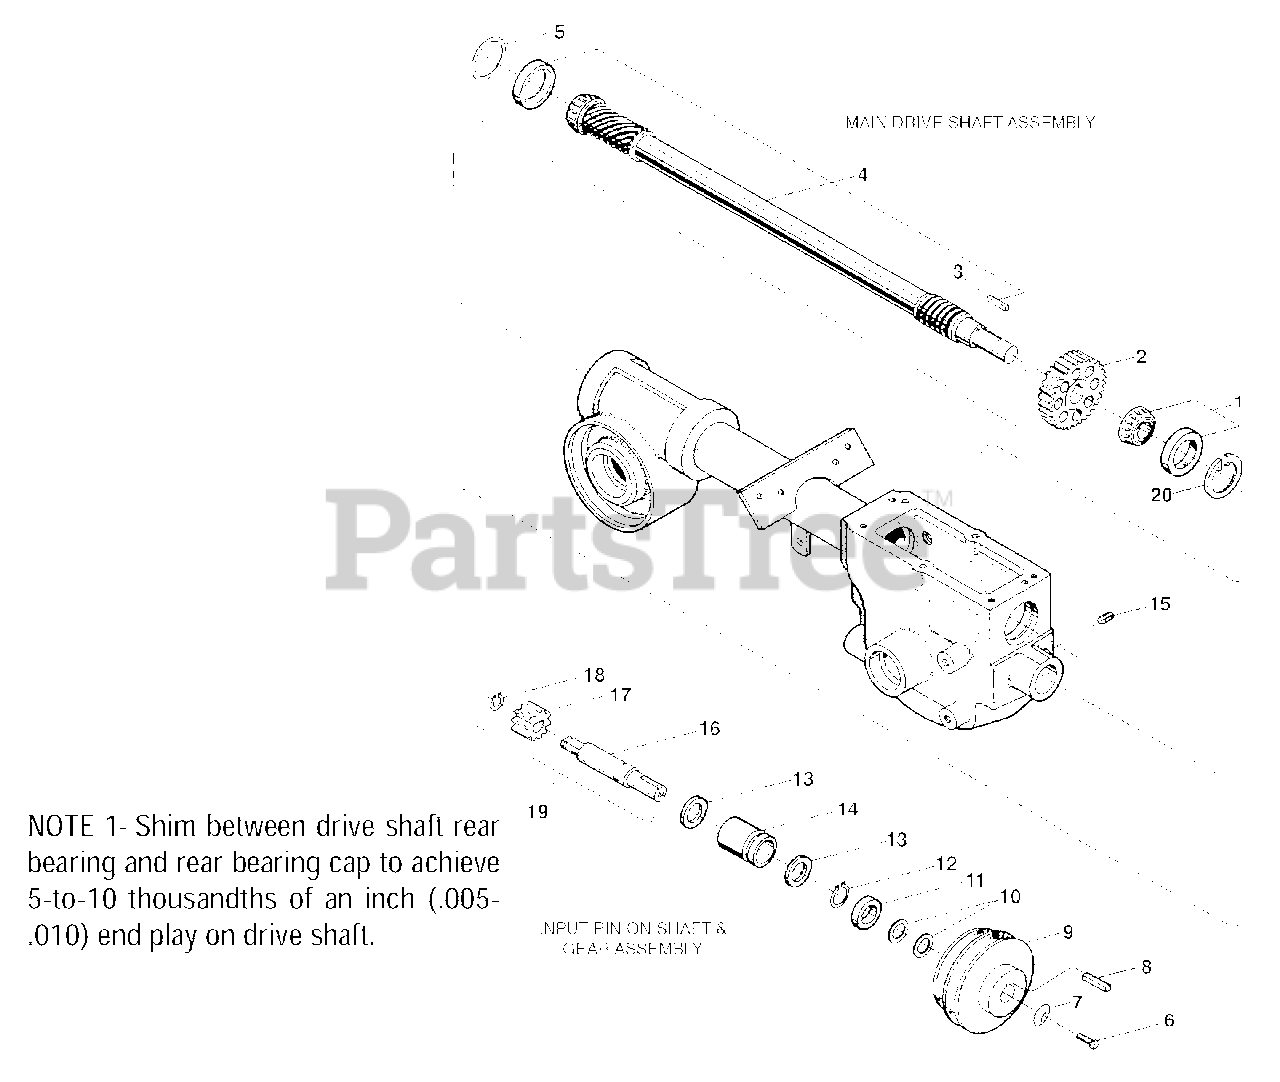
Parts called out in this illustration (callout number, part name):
1	Bearing-Tapered roller with race
2	Gear-Spur, main drive shaft
3	Key, 3/16 sq. x 1
4	Drive Shaft-with integral, single-lead worm at front and six-lead worm at rear
5	Shim-Rear bearing cap, .010 thick
5	Shim-same as above, but .030 thick
5	Shim-same as above, but .005 thick
6	Hex Hd. Screw, 5/16-24 x 1-1/8
7	Washer-Disc spring (concave surface faces pulley)
8	Key, 3/16 sq. x 1-1/
9	Pulley-Transmission drive
10	Support Washer
11	Oil Seal-Input pinion shaft, front
12	Ring-Retaining (snap ring), external
13	Thrust Washer
15	Set Screw, 5/16-18 x 3/8
16	Input Pinion-steel shaft
17	Gear-Input pinion
18	Retainer-Snap ring, external
19	Pinion Assy
20	Retainer-Snap ring, internal
